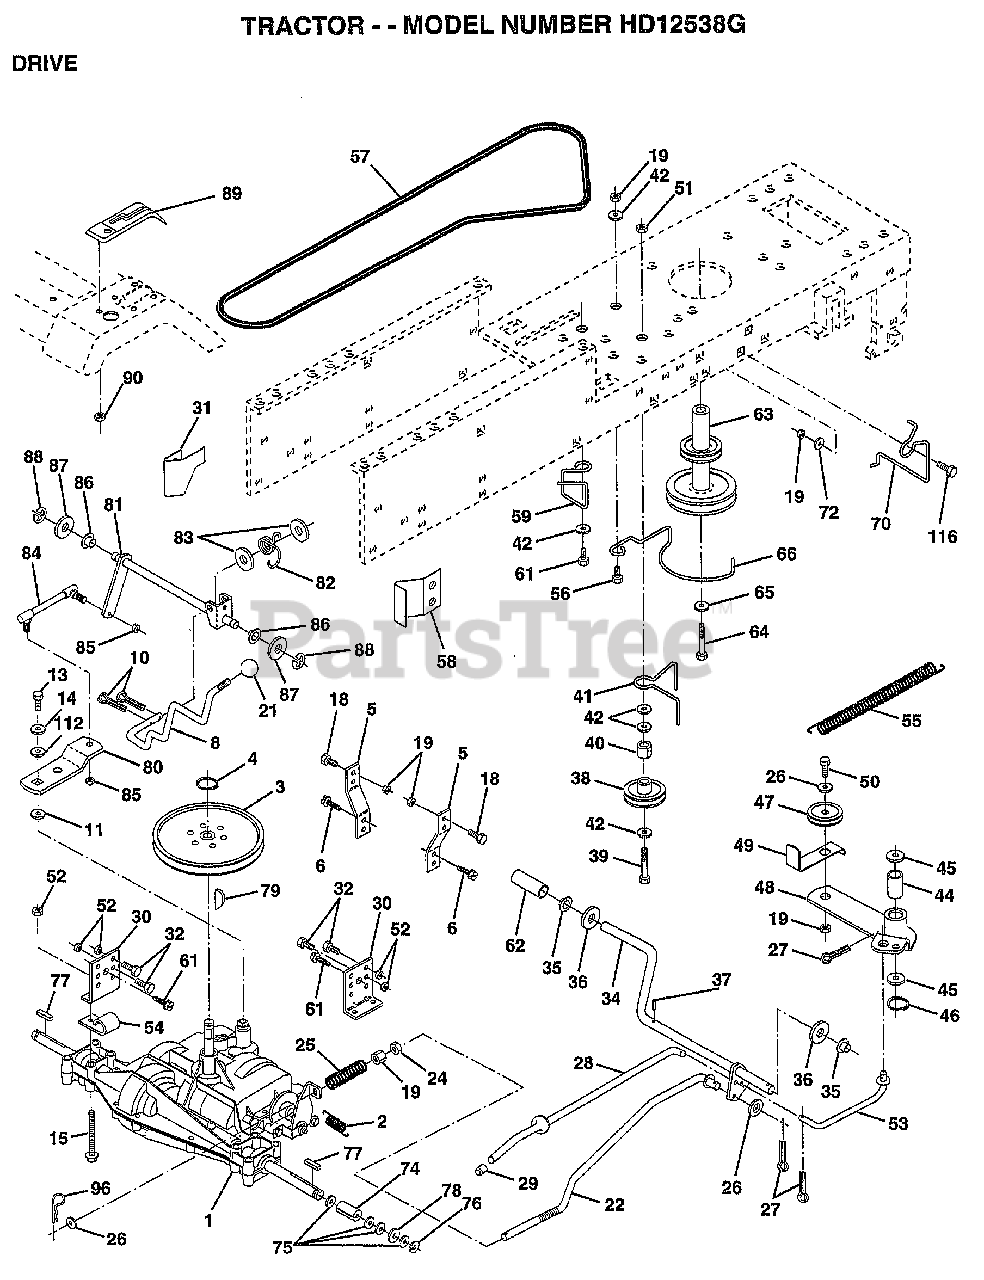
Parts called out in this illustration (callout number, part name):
2	SPRING.BRAKE.RETU
3	PULLEY TRANS
5	STRAP TORQUE
6	SCREW
7	BRKT.SADDLE.SHIFT
8	SHIFT ROD
10	PIN COTTER 1/8
11	WASH-SHFT PLT LT
12	WASHER
13	BOLT.1/4-28.W/PAT
14	LOCKWASHER
18	BOLT
19	NUT
21	KNOB T (1/2-HOLE)
22	BRAKE ROD
24	NUT
25	SPRING ROD LT
26	WASHER
27	COTTER PIN
28	ROD.BRAKE.PARK.LT
29	PLUNGER CAP T
30	TRANSAXLE MTG BKT
31	"KEEPER,BELT LH T"
32	BOLT
34	SHAFT ASM-PEDAL F
35	NYLON BEARING
36	WASHER LT
38	PULLEY.IDLER.FLAT
39	BOLT
40	SPACER T
42	WASHER
48	BELLCRANK.CLUTCH
49	RETAIN BELT
53	"LINK, CLUTCH T"
54	CLIP T
55	"SPRING, RETURN LT"
58	"KEEPER,BELT RH T"
59	KEEPER BELT CNTSP
61	SCREW
62	PEDAL COVER T
63	PULLEY.ENGINE
64	BOLT
65	LOCKWASHER
66	KEEPER-BELT
70	KEEPER BELT ENG
72	WASHER
74	SPACER AXLE
76	E-RING LT
77	SQUARE KEY
78	WASHER
112	WASHER LT
113	"STRAP,TORQUE"
116	BOLT RDHD 3/8-16
145	BOLT.HEX.FLGHD
149	SPACER RETAINER
150	BUSHING.NYLON
151	WASHER
